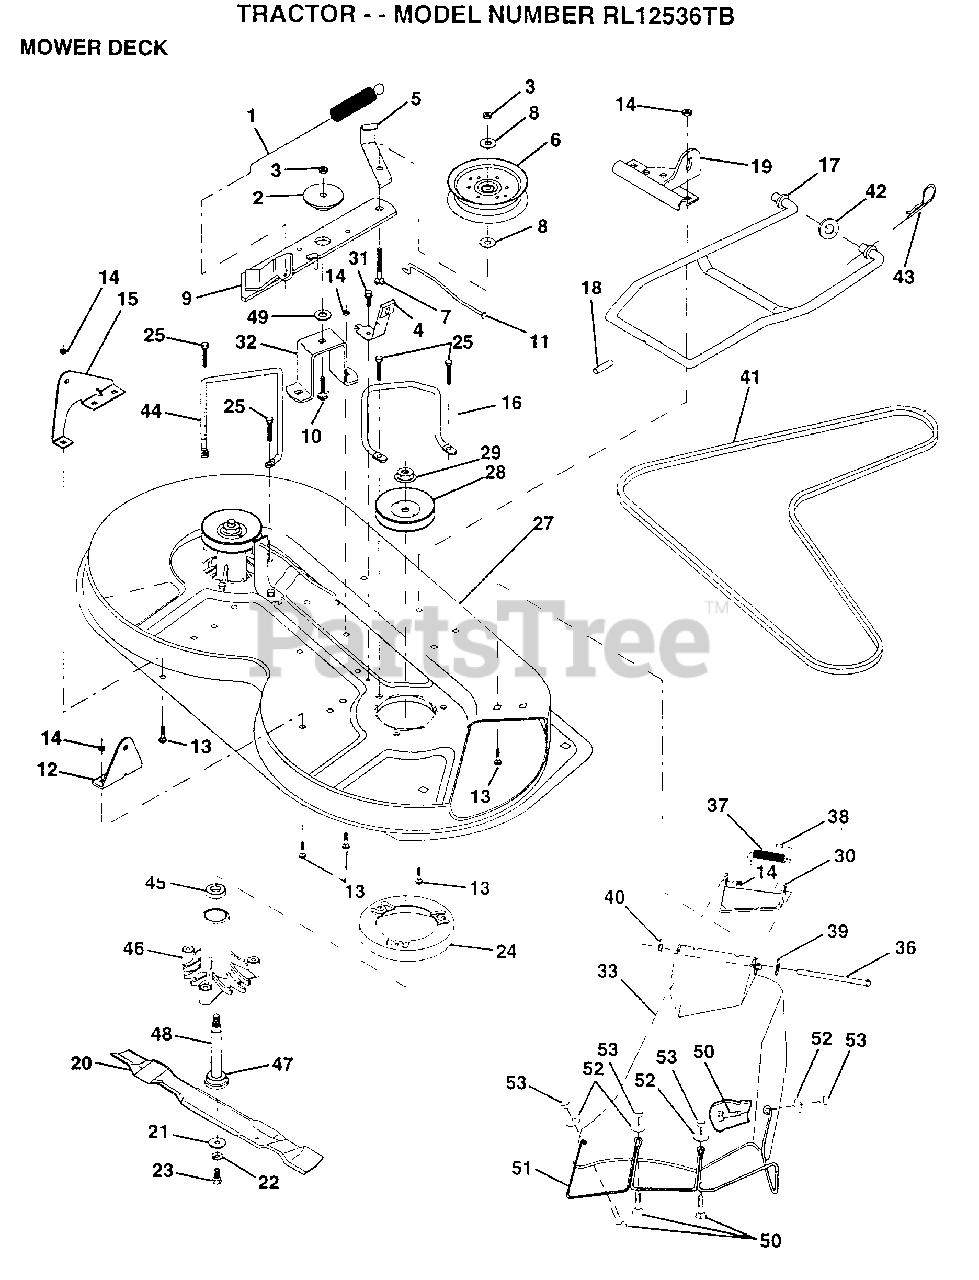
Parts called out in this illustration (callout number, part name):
1	SPRING CLUTCH MWR
2	SPACER RETAINER
4	BRAKE ASM
5	IDLER BELT GUIDE
6	PULLEY IDLER
7	BOLT
8	WASHER
10	BOLT.3/8-14X1.25
11	BRAKE ROD
12	"BRKT,LIFT REAR"
13	BOLT
15	"BRKT,LIFT REAR LH"
16	"KEEPER-BELT,RH"
17	MOWER LINK STAB
18	"PIN,GROOVE"
19	"BRKT,LINK STABILI"
20	"BLADE.36"" HIPERF"
21	WASHER.HARD.BLADE
23	BLADE BOLT
24	STRIPPER RND MWR
28	PULLEY.MAND.36/46
31	SCREW LT
32	"SUPT,IDLER ARM"
33	SHIELD.DEFL.36TUV
36	HINGE ROD
37	SPRING TORSION
38	CAP-SLEEVE LT
39	WASHER
40	NUT PUSH M
41	V-BELT.PRIM.78.5.
43	RETAINER.SPRING
44	KEEPER BELT LH
45	BEARING
46	HSG ASM MANDREL
47	BEARING.BALL
49	HARDENED WASHER
50	SCREW
51	GUARD.DFTR.MWR.36
53	ACORN NUT RB
